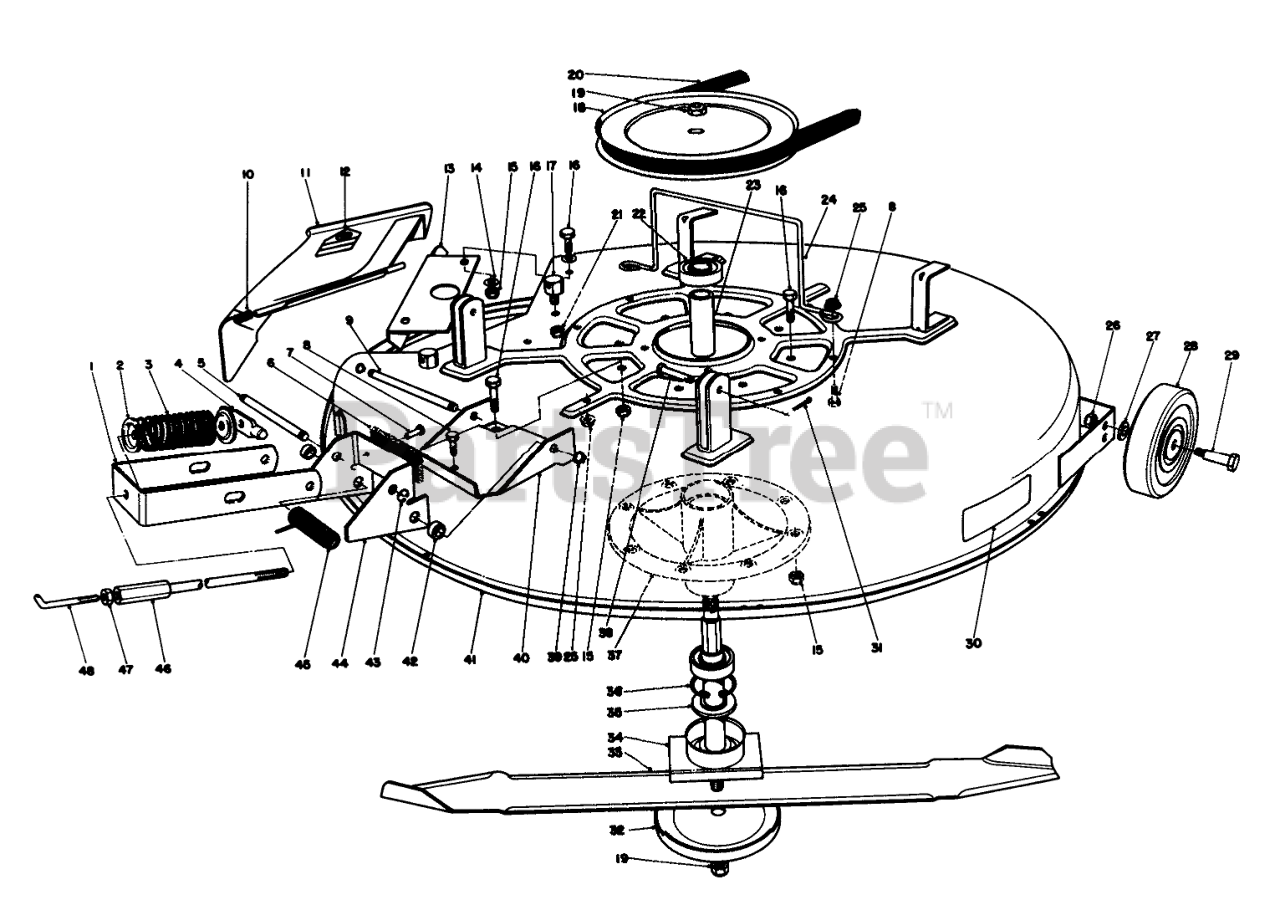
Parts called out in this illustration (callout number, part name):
1	Bracket-Engagement
2	RETAINER-SPR. TOP
3	SPRING-COMPRESSION
4	SHAFT-DECK ADJ.
5	Pin-Clevis
6	Pad-Brake
7	RIVET .187 X 7/16 BRASS
8	SCREW-HH
9	CLEVIS PIN
10	SPRING
11	Deflector Assembly (Incl. Ref. #12)
12	DECAL-DANGER
13	Baffle Deck
14	WASHER-PLAIN
15	NUT-LOCK, NI
16	Screw
17	POST-PIVOT
18	PULLEY
20	V-BELT, DECK
21	NUT-LOCK, SIDE
22	BEARING-BALL
23	Spacer-Bearing
24	GUIDE-BELT
25	NUT-LOCK, HHF
26	NUT-LOCK, NI
27	WASHER-FLAT
28	WHEEL-DECK
29	BOLT-WHEEL
30	DECK DECAL
31	PIN-COTTER
32	Cup
33	Blade
34	SPINDLE SHAFT WA
35	SPACER-SPINDLE
36	RING-RETAINING
37	SPINDLE
38	PIN-CLEVIS
39	RING-RETAINING
40	DECK ENGAGE CHANNEL R
41	Cutter Deck
42	DECK BRAKE SPACER
43	E-RING
44	Support Deck Brake Assembly (Incl. Ref. #6 & 7)
45	SPRING
46	ADJ HUB WA
47	NUT-JAM
48	ADJ. ROD
